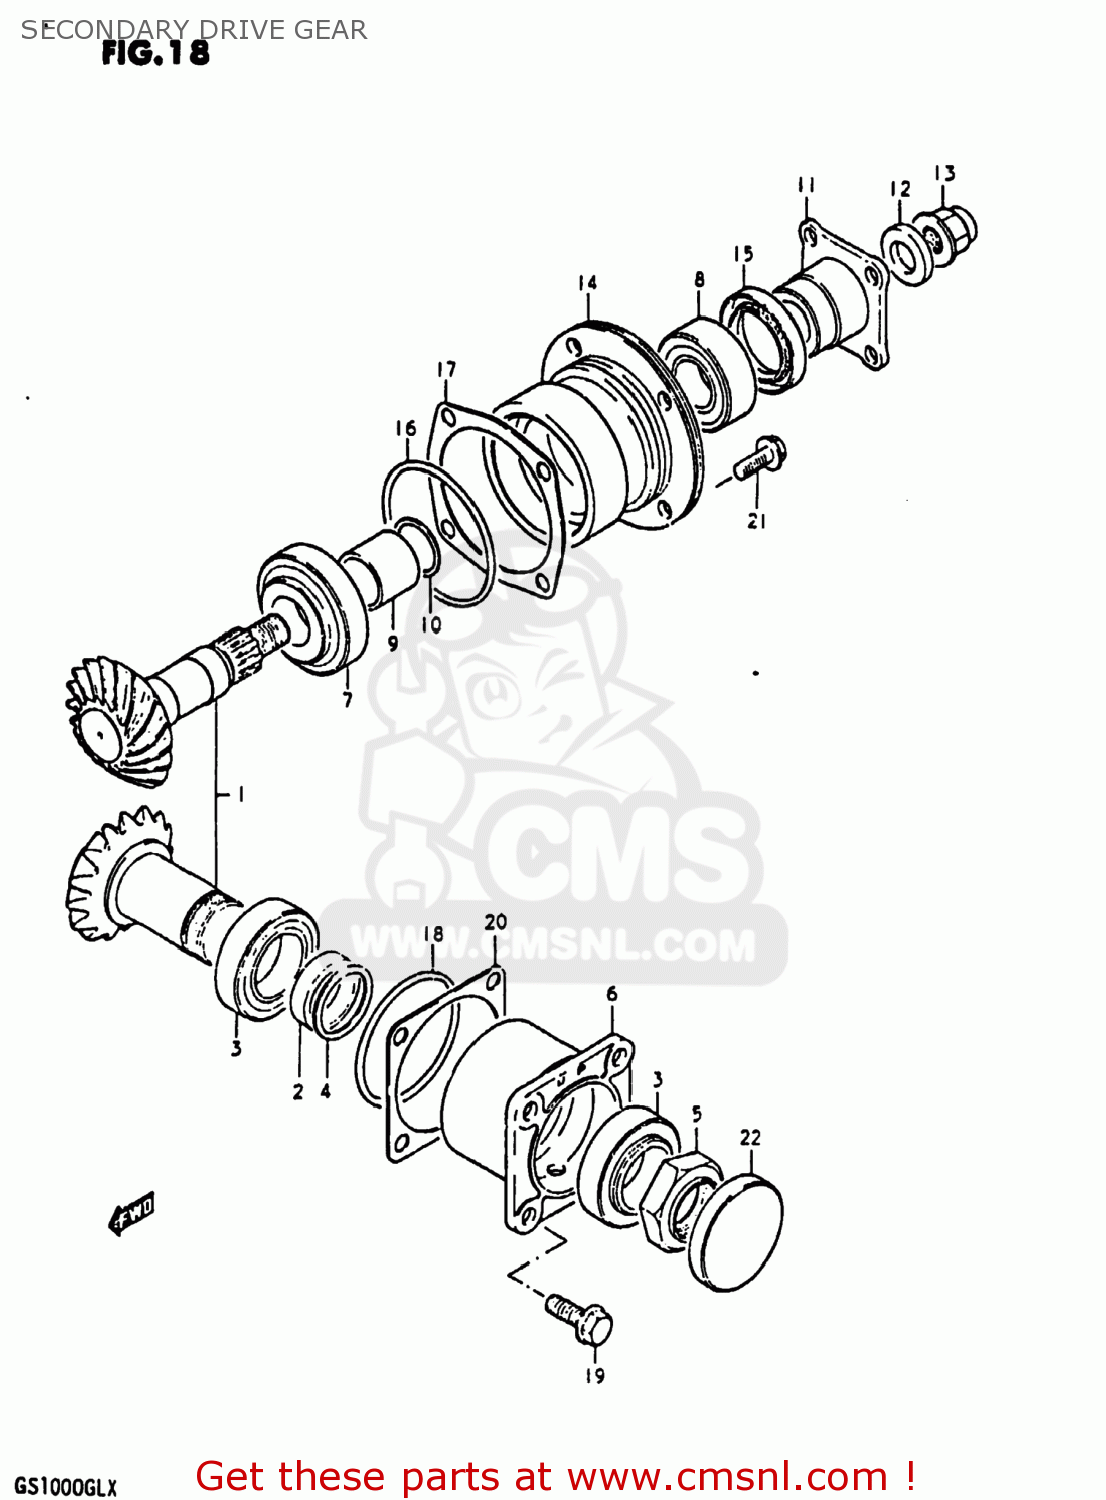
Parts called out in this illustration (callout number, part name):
0	2ND GEAR & HOUSING SET
1	SECONDARY GEAR SET
2	SPACER (32.4X38X12.5)
3	BEARING(32X58X17)
4	SHIM(32X38X2)
5	NUT
6	HOUSING,SECONDARY DRIVE
7	TAPER,ROLLER BEARING
8	BEARING
9	SPACER (25.2X30X40)
10	SHIM (25X30X2
11	FLANGE,UNIVERSAL JOINT
12	WASHER(14X29X4)
13	NUT
14	HOUSING,SECONDARY DRIVE
15	SEAL,OIL(35X52X9)
16	O RING(D:3.1,ID:69.4)
17	SHIM,DRIVEN GEAR HOUSING
18	O RING(D:2.4,ID:62.6)
19	BOLT
20	SHIM,SECONDARY DRIVE
21	BOLT
22	PLUG
